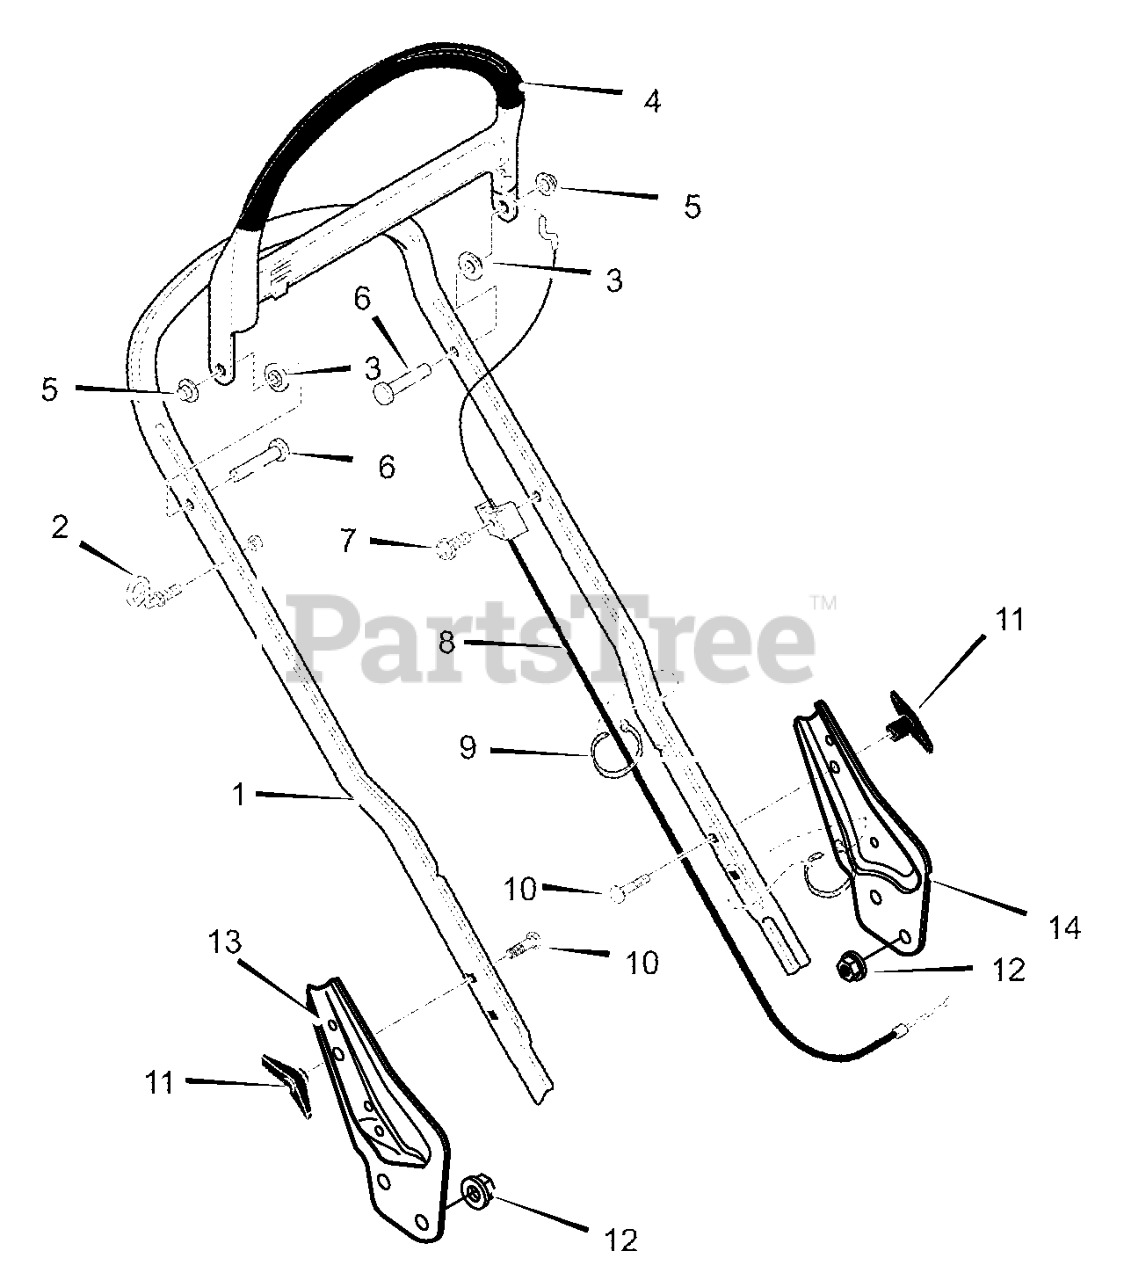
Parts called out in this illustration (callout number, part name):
1	Handle, Upper
2	Guide, Rope
4	Lever, Stop
5	Push-On Cap
6	Pin, Clevis
8	Cable, Stop
9	Strap, Tie
10	Bolt, Carriage
11	Wingnut
12	Nut
13	Bracket, Right Handle
14	Bracket, Left Handle
